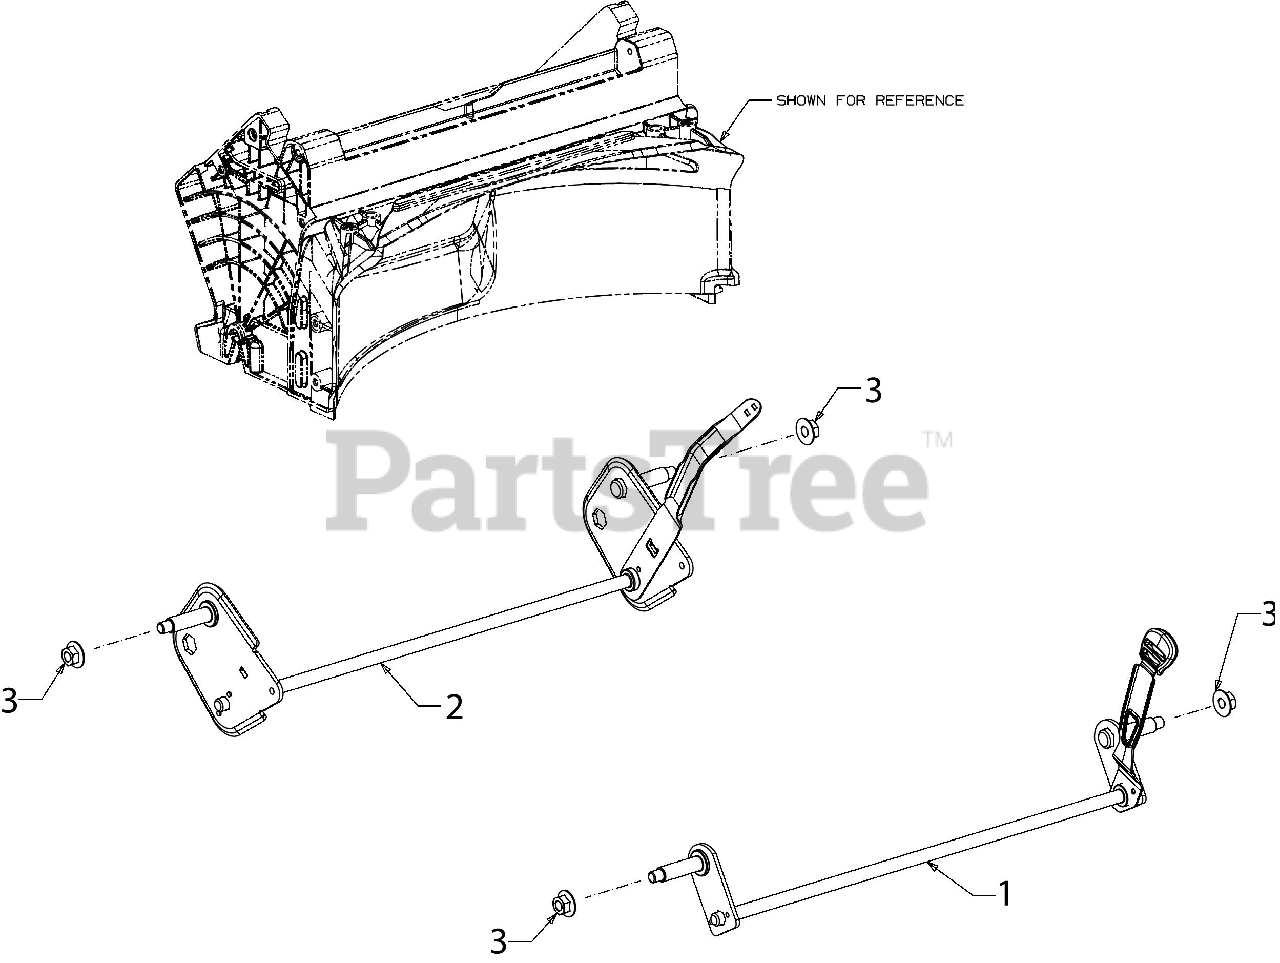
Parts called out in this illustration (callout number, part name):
1	FRONT AXLE ASSEMBLY
2	REAR AXLE ASSEMBLY
3	FLANGE LOCK NUT
